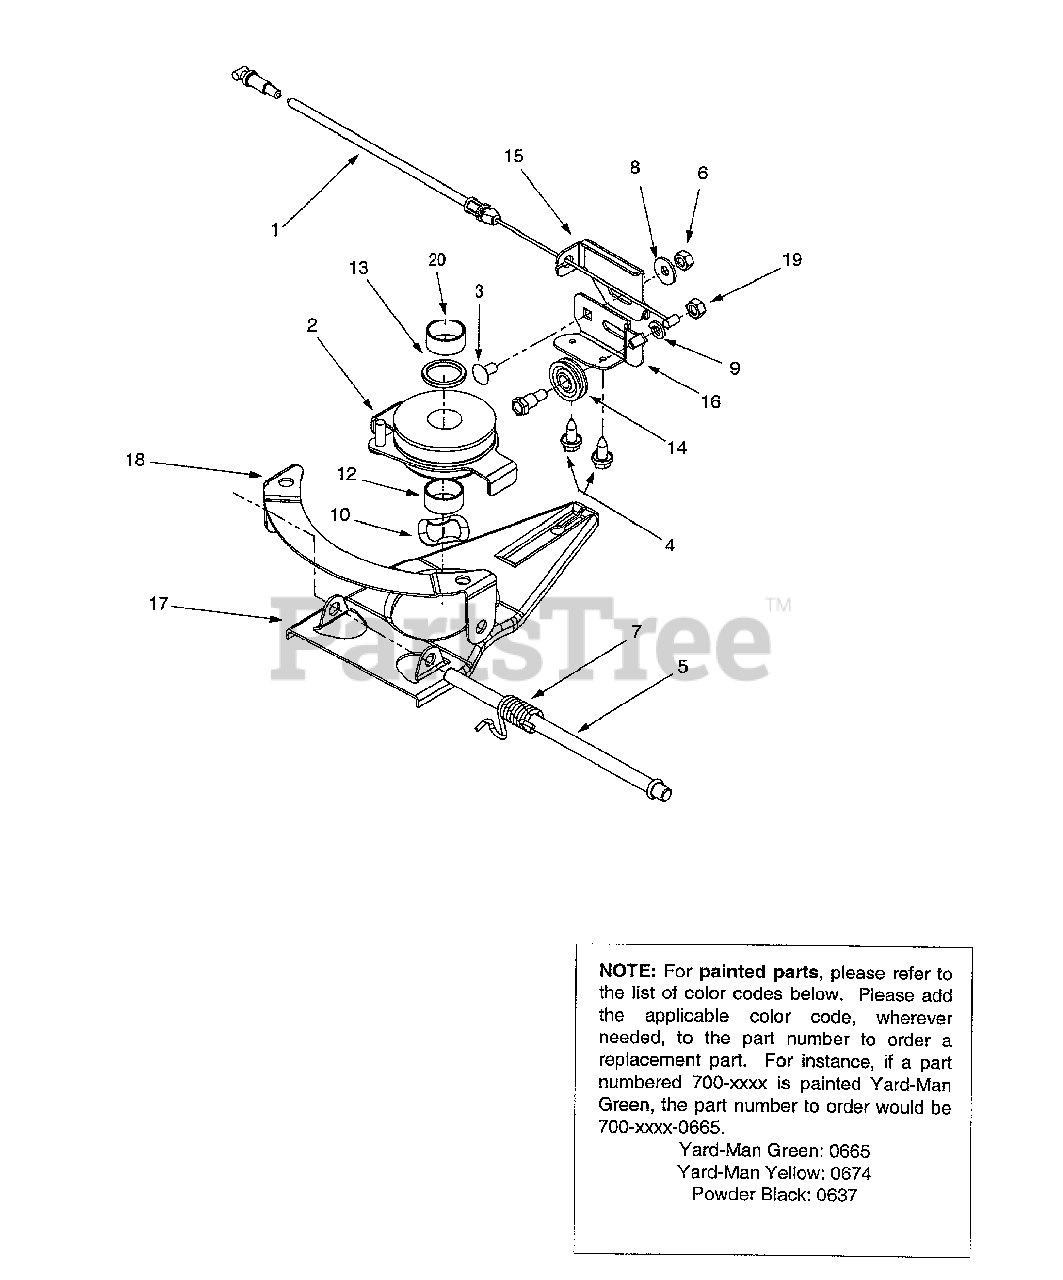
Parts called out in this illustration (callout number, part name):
1	Speed Selector Cable, 53"
2	Multi-Speed Pulley Assembly
3	Carriage Bolt, 1/4-20 x. 5
4	Self-Tapping Screw, 1/4-20 x .625
5	Pivot Shaft
6	Nut, 1/4-20
7	LH Torsion Spring
8	Bell Washer, .265 x .75 x .062
9	Lock Washer, 1/4
10	Wave Washer, 1.38 x .88 x .029
12	Sleeve Spacer, .88 ID x 1 OD x .48
13	Sleeve Spacer, .88 ID x 1.13 OD x .12
14	Cable Roller
19	Hex Nut, 1/4-20
